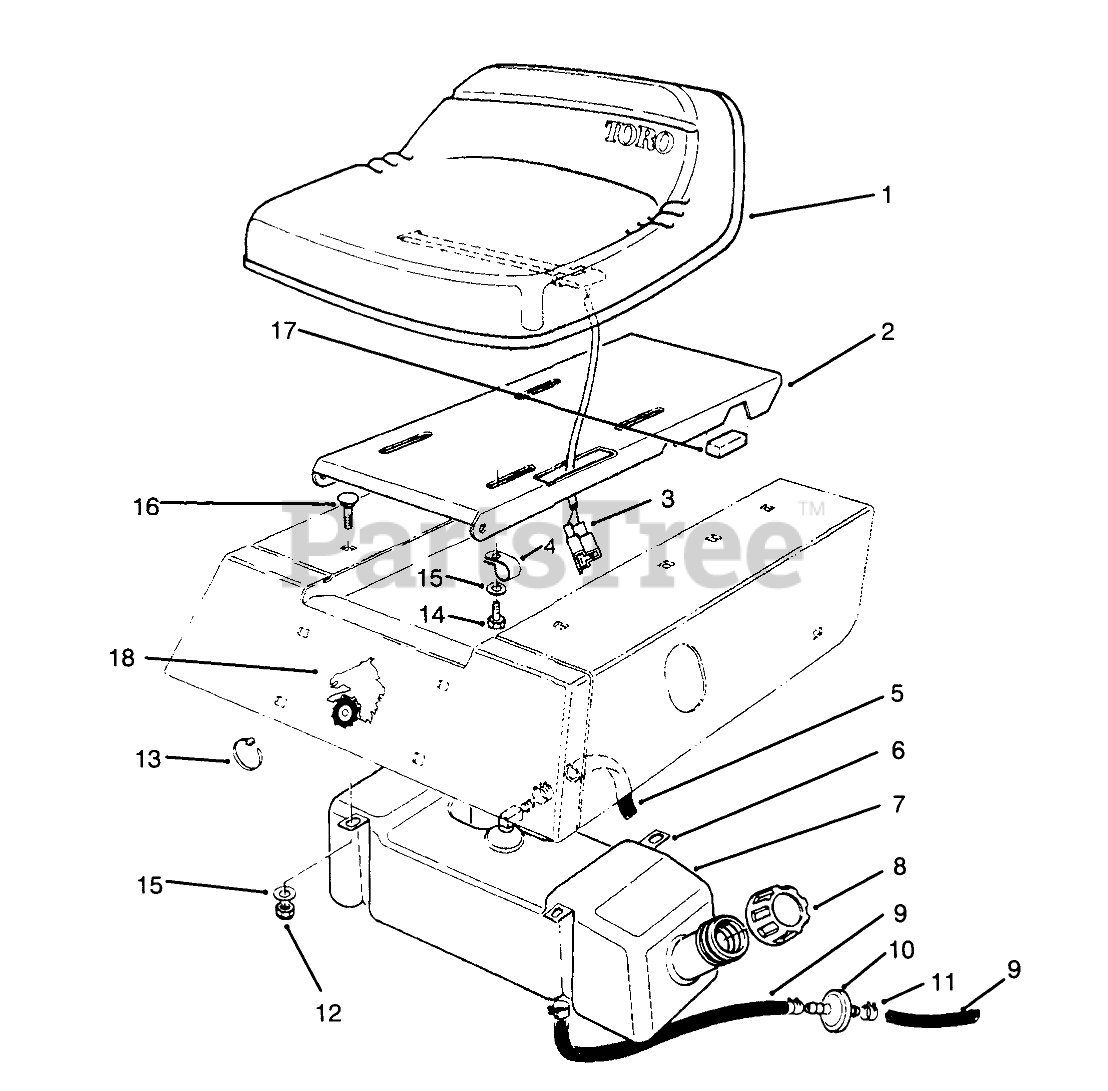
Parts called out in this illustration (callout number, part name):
1	Seat
2	BASE - SEAT
3	SWITCH-SEAT
4	CLIP-FUEL LINE
5	HOSE-FUEL
6	STRAP-GAS TANK
7	TANK-GAS
8	GAS CAP ASM
9	HOSE-FUEL
10	FILTER-FUEL
11	CLAMP-HOSE
12	NUT-LOCK, NI
13	TIE-CABLE
14	SCREW-HH
15	WASHER-PLAIN
16	SCREW-CARR
17	PAD-ISOLATOR
18	DECAL - W.H. INSIGNA
